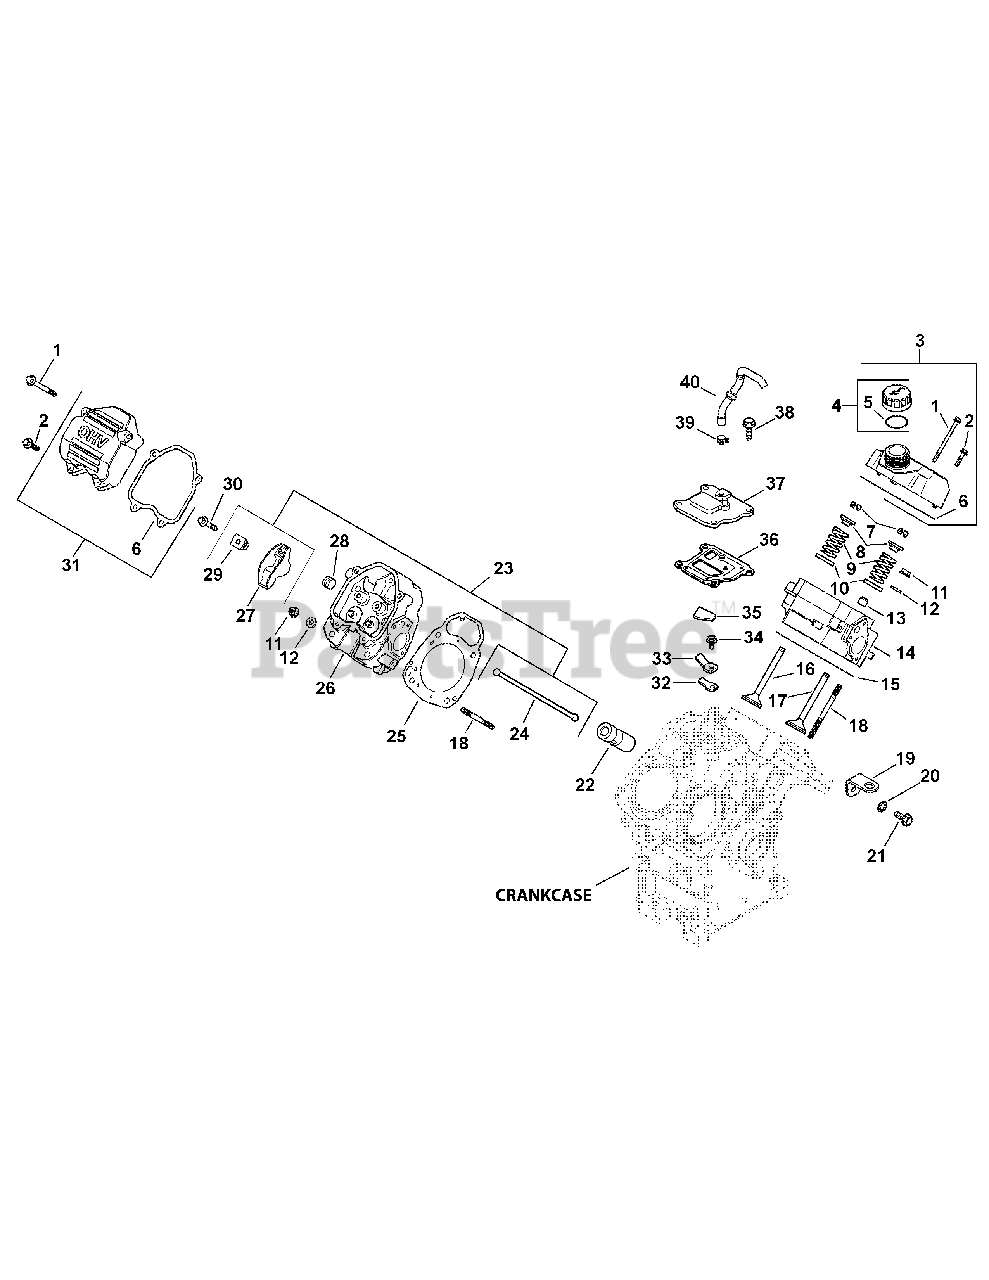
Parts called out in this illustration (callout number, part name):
1	Screw, Flg, M6 x 1.0 x 50
2	Screw, Flg, M6 x 1.0 x 25
3	Kit, Rocker Cover (Oil Fill)
3	Rocker Cover & Gasket (Oil Fill)
4	Kit, Oil Fill Cap (Yellow)
5	O-Ring, Oil Pick-up
6	Gasket, Valve Cover
7	Kit, Retainer
8	Cap, Valve Spring
9	Spring, Valve
10	Retainer
11	Nut, Flg, M8 x 1.25
12	Washer, Flat, 5/16"
13	Seal, Valve Stem
14	Kit, Cylinder Head (#1 Side)
15	Kit, Cyl Head Gasket (#1 Side)
16	Valve, Exhaust (Std)
16	Valve, Exhaust (.25)
17	Valve, Intake (Std)
17	Valve, Intake (.25)
19	Strap, Lifting
20	Washer, Int Tooth Lock 1/4
21	Screw, Flg Thd Frm M6x1.0x16
22	Kit, Hyd Valve Lifter
23	Kit, Valve Train
25	Kit, Cyl Head Gasket (#2 Side)
26	Kit, Cylinder Head (#2 Side)
28	Plug, Pipe Ctsk, 3/8
29	Pivot, Rocker Arm
30	Screw, Rocker Arm Pivot
31	Kit, Rocker Cover
32	Reed, Breather
33	Retainer, Reed
34	Screw, Flg Thd Frm, M5x.8x10
35	Filter, Breather
36	Gasket, Breather
37	Cover, Breather
38	Screw, Flg Thd Frm, M6x1.0x20
39	Clamp, Band Spring Hose
40	Hose Assembly, Breather
